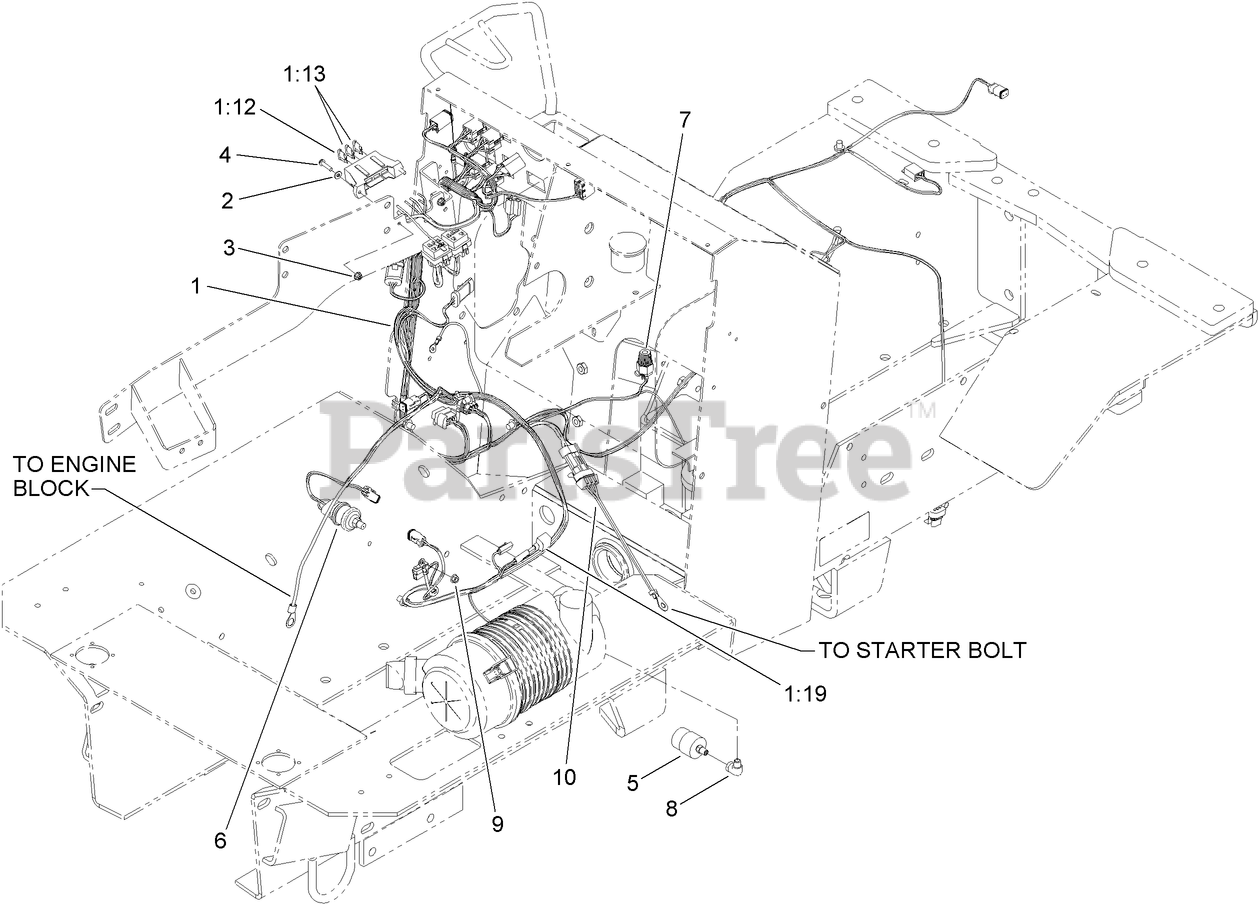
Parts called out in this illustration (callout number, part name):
1	HARNESS-WIRE, MAIN
1:12	FUSE-2 AMP
1:13	FUSE-BLADE, 10 AMP
1:19	RESISTOR-75 OHM
2	WASHER-FLAT
3	NUT-HF
4	SCREW-HWH
5	SWITCH-PRESSURE, VACUUM
6	SWITCH-PRESSURE, OIL
7	SWITCH-TEMP, 200 DEGREE
8	ELBOW
9	NUT-HF
10	HARNESS-WIRE, FUSIBLE LINK
